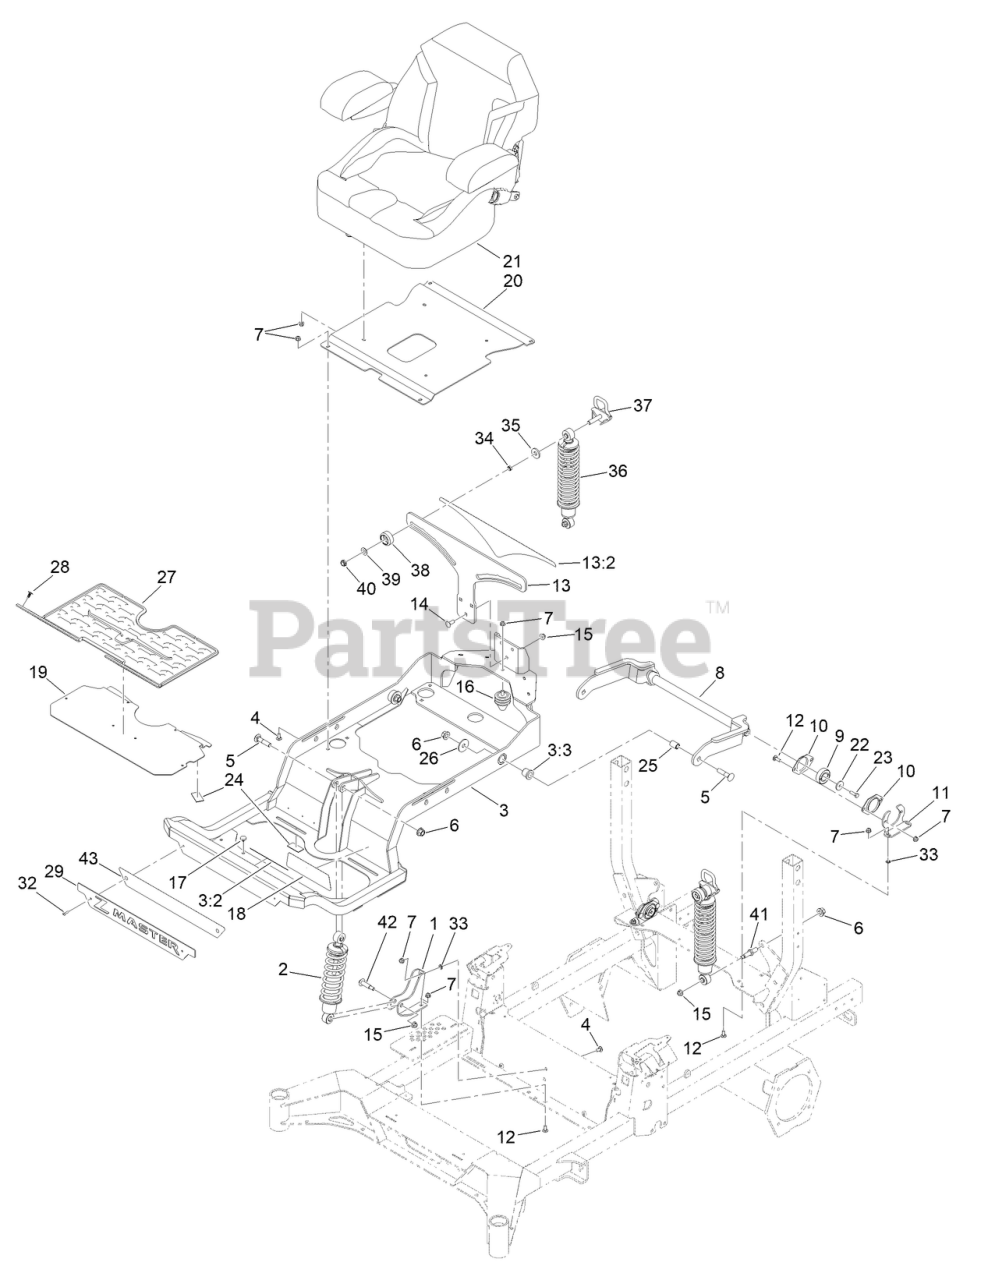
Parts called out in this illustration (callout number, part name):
1	BRACKET-SHOCK, FRONT LOWER
2	HD SHOCK/SPRING ASM
3	SUBFRAME ASM W/DECAL
3:2	DECAL-DANGER
3:3	BUSHING-FLANGE
4	SCREW-CARR
5	SCREW-CARR
6	NUT-LOCK
7	NUT-HF, NI
8	ARM-TRAILING
9	BEARING
10	HOUSING-BEARING, FLANGE
11	BRACKET-BEARING
12	BOLT-CARR
13	BRACKET-MOUNTING
13:2	DECAL-ADJUSTMENT, RIDE
14	SCREW-CARR
15	NUT-HF, NI
16	ISOLATOR
17	BUMPER
18	DECAL-MYRIDE
19	FLOORPAN
20	PAN-SEAT
21	STANDARD SEAT ASM
22	WASHER-FLAT
23	SCREW-HH, THREAD LOCKING
24	PAD-RUBBER
25	SPACER-ALUMINUM
26	WASHER-THRUST
27	FLOORMAT-MYRIDE
28	PLUG-PLASTIC
29	PLATE-BADGE [BLACK]
32	RIVET-TRIFOLD
33	NUT-PUSH
34	BEARING-SLEEVE
35	WASHER-PLASTIC
36	SHOCK/SPRING ASM
37	CAM LOCK ASM
38	KNOB-LOCK, CAM
39	WASHER-ADJUSTING
40	NUT-HEX
41	BOLT-SHOULDER
42	BOLT-SHOULDER, HWH
43	DECAL-BACKER PLATE
